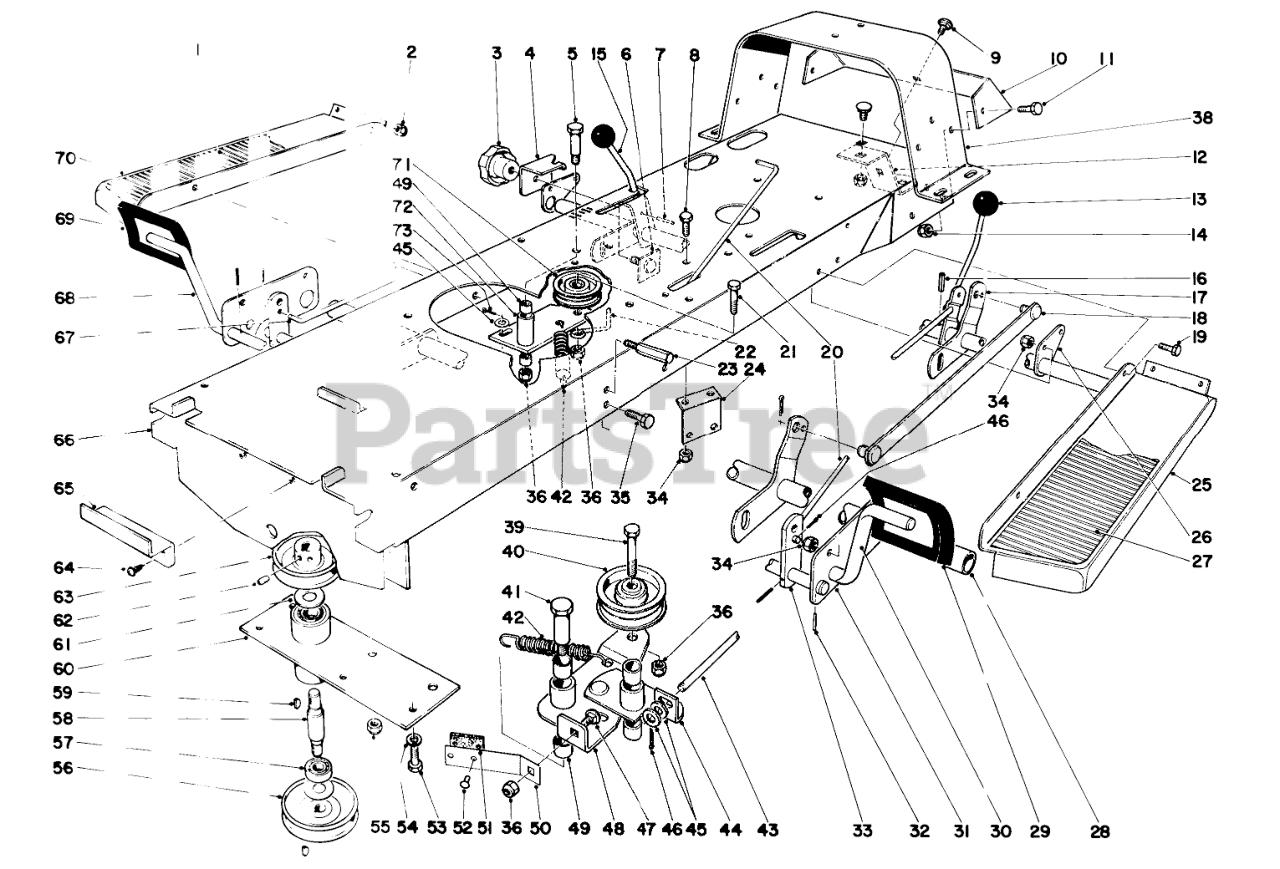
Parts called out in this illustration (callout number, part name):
1	Foot Pad
2	NUT-KEPS
4	Slide Height Adj.
5	Shoulder Bolt
6	Knob Plate
7	PIN-ROLL
8	SCREW-HH
9	SCREW-CARR
10	Frame Member Rear
11	SCREW-HH
12	Bracket Hitch
13	Knob
15	Rod Control Hgt. Adj.
16	Roll Pin
17	Rear Height Adj. Tube
18	Height Adj. Link
19	SCREW-HH
20	Brake Rod
21	SCREW-HH
22	Belt Retainer
23	Pedal Stop
24	Belt Guide
25	Footrest
26	Bracket Tube
27	Foot Pad L.H.
28	Front Height Adj. Tube
29	CLUTCH PAD
30	Clutch Pedal
31	Plate Tube
32	PIN-SPRING
33	Arm Lever
34	Nut
35	SCREW-HH
38	Rear Support
39	SCREW-HH
40	Pulley
41	Shoulder Bolt
42	Spring Tension
43	Clutch Rod Blade
44	Pivot Bracket
45	WASHER-FLAT
46	PIN-COTTER
47	SCREW-CARR
48	Idler Plate
49	Bushing
50	Clutch Brake
51	BLADE BRAKE LINING
52	Rivet
53	SCREW-HH
54	WASHER-LOCK
56	Pulley
57	Bearing
58	Pulley Shaft
59	KEY-WOODRUFF
60	Pulley Tube
61	Bearing Washer
62	SCREW-SET, HSH
63	Pulley
64	10-24X1/2 OVAL HD SEMS
65	Spring Clip
66	Frame
67	Clutch Rod
68	Brake Pedal
69	PAD-BRAKE
70	Footrest
71	Pulley
72	Idler Arm
73	PIN-COTTER
